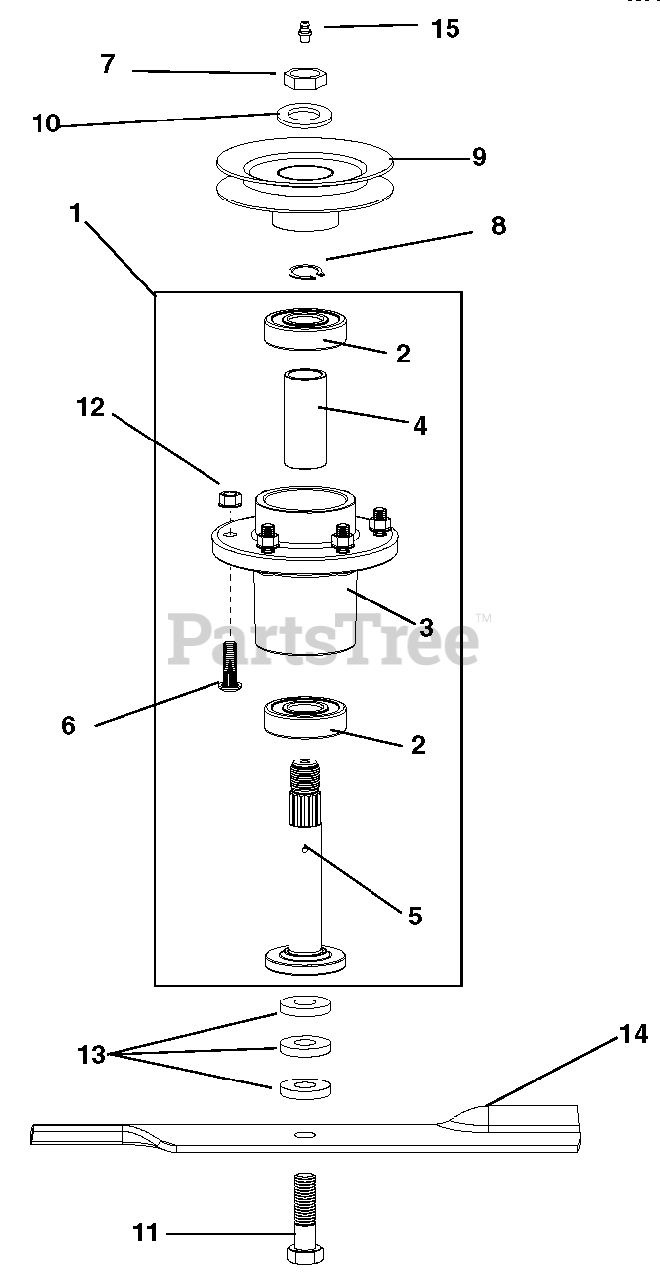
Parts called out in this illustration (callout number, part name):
1	Spindle Assembly (Includes 2, 3, 4, 5, & 15)
2	Bearing, 6305LLC
3	Casting, Spindle W/STUDS
4	Spacer, 1.250 x 1.000 x 2.780
5	Shaft, Spindle .75-16
6	Bolt, .38-16 x 1.25 Round Head Square Neck
7	Nut, 3/4-16 Crown Lock
8	Ring, Retainer
9	Pulley, Cutter Housing - Refer to Deck Assembly on page 22 or page 24
10	Washer, .75 x 1.312 x .120
11	Bolt, 5/8-11 x 2.00 Hex 8
12	Nut, .38-16 Standard Hex Grade 5
13	Washer, .630 x 1.50 x .250 Flat
14	Blade, 16.500 x .80 Lift (48-Inch Decks)
15	Zerk, Grease S/O
